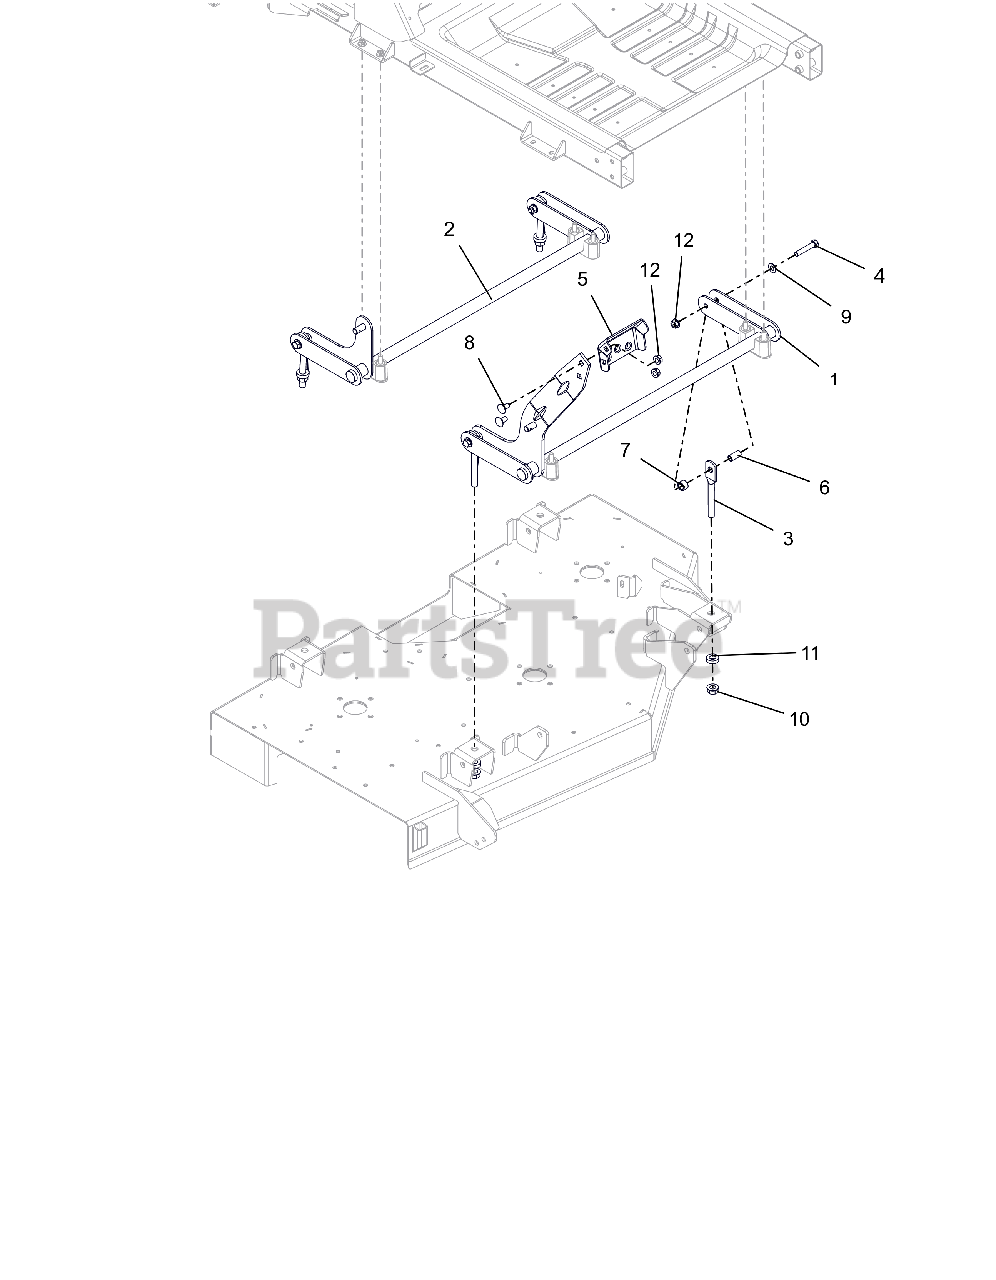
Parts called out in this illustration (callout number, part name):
1	WLDMT, FRONT DECK LIFT PIVOT
2	WLDMT, REAR DECK PIVOT
3	LINK,DECK (HOLE-LONG)
4	BLT, HEX .38-16X2.00 G8 ZCC
5	PEDAL, DECK LIFT (BOLT ON)
6	BSHG-SLV .385X.500X1.045
7	BSHG-SLV .510X.751X.475
8	BLT,RHSN .38-16X.75 G5 BFP
9	WSHR,FLT .406X.812X.065 ZCC
10	NUT-LK-CTR-FLG .500-13 GG ZCC
11	WASHER, RUBBER
12	NUT-LK-CTR-FLG .375-16 GF ZCC
